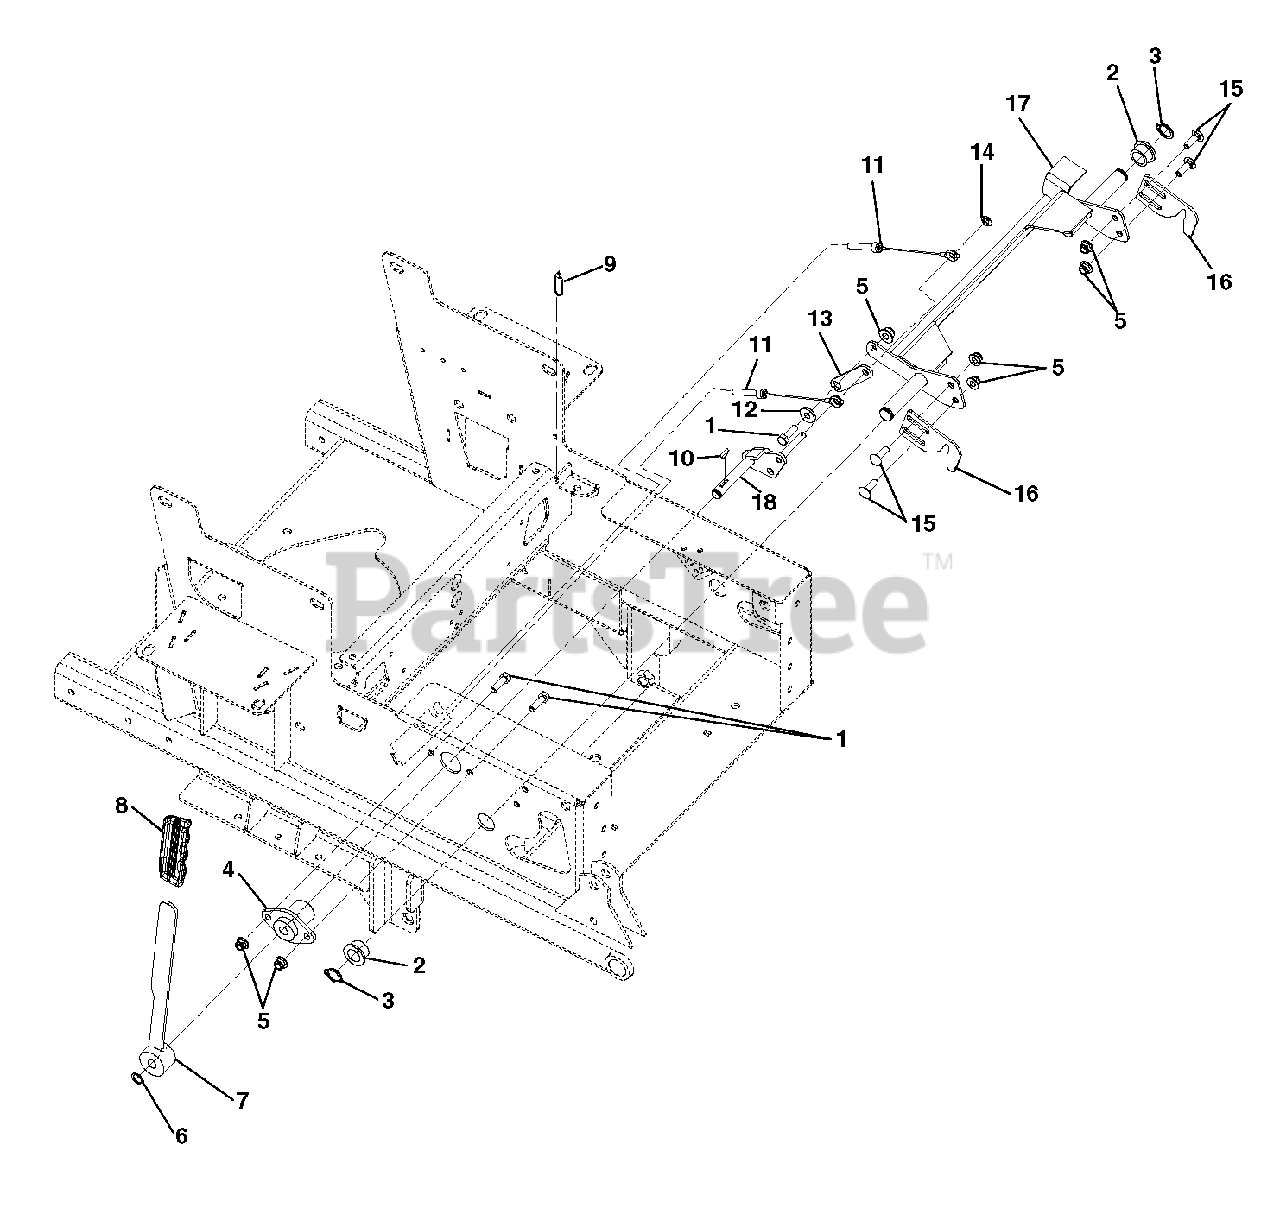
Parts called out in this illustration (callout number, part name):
1	Bolt, Hex .31-18 x 1.00 Grade 5
2	Bushing, Flange .750 x 1.000 x .625 x 1.250
3	Ring, Retaining-External .689 x .077
4	Bushing, Flanged
5	Nut, .31-18 Nyloc Flange
6	Ring, Retaining-External .500 x .050
7	Weldment, Parking Brake Arm
8	Grip, Parking Brake
9	Cable Tie
10	Key, Woodruff .13 x .63 HRD#5
11	Cable, Brake Actuating
12	Bushing, Flange .325 x .499 x .26 x .88
13	Plate, Neutral Interlock
14	Nut, Push .312
15	Bolt, Round Head Square Neck .31-18 x 1.00 Grade 5
16	Neutral Lock Latch
17	Weldment, 100I Neutral Lock
18	Weldment, Park Brake Arm
